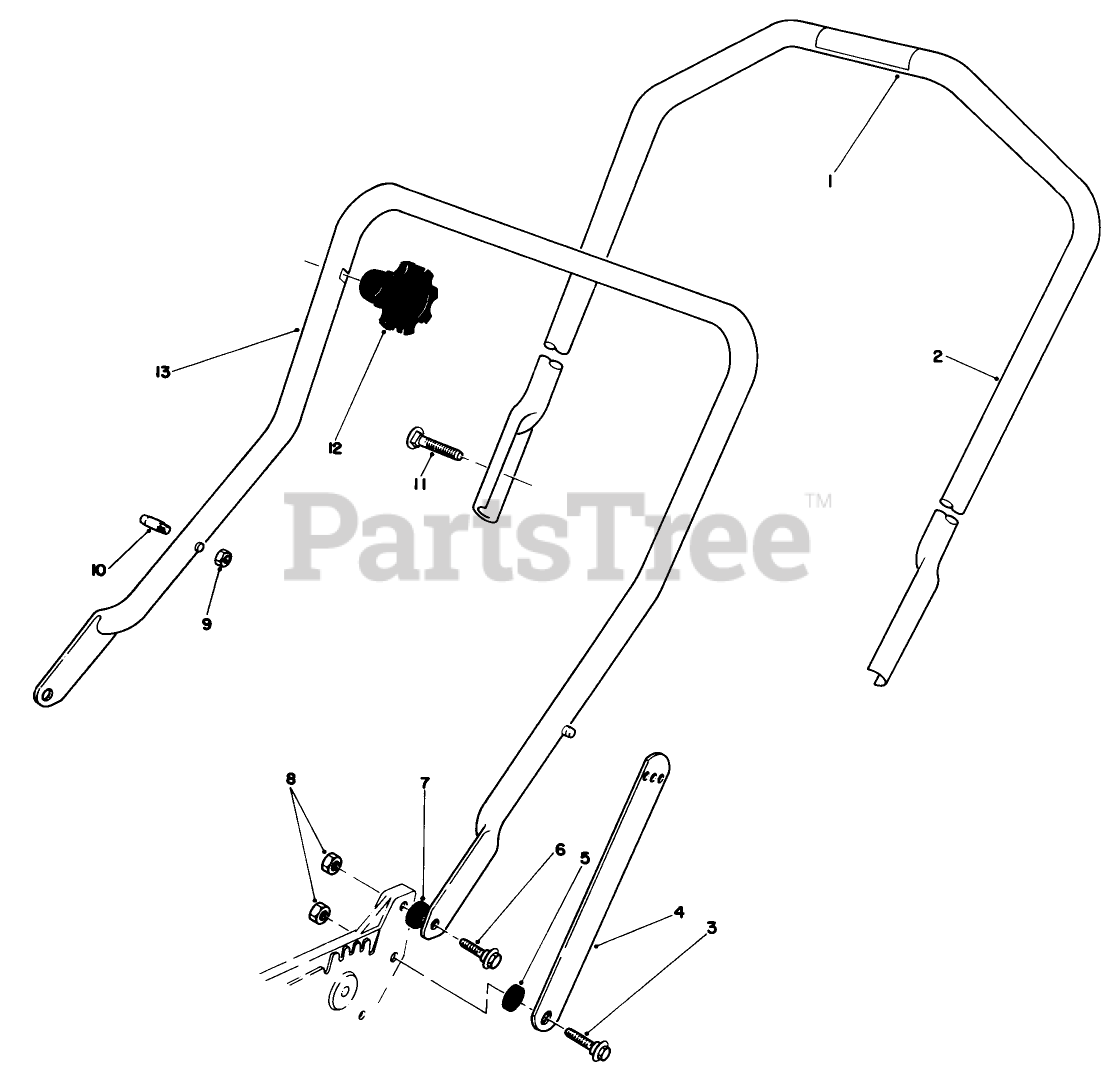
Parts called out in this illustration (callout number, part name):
3	SCREW-SHOULDER
5	SPACER
6	SCREW-SHOULDER
7	SPACER
8	NUT-LOCK, NI
9	NUT-LOCK, NI
10	HANDLE PIN
